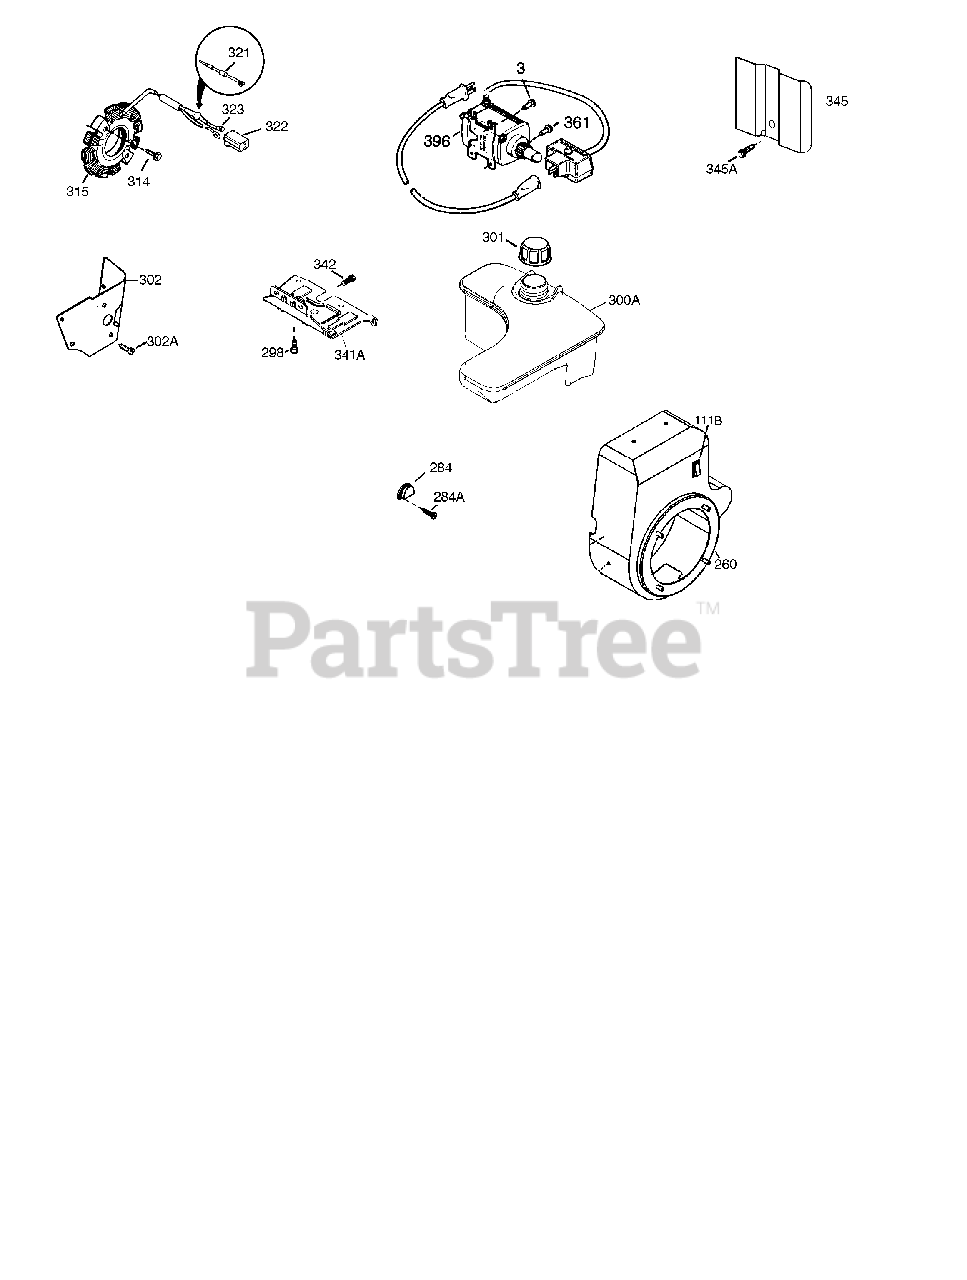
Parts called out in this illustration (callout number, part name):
260	Blower Housing
298	Screw, 1/4-15 x 3/4"
301	Fuel Cap (Red)
314	Screw, 1/4-20 x 3/4"
315	Alternator Coil (3 Amp) Incl. 321 - 3 23
322	Connector Body
323	Terminal
325	Wire Clip
341	Fuel Tank Bracket
342	Screw, 5/16-18 x 7/8"
345	Heat Baffle
370	Identification Decal
370I	Warning Decal (Bilingual)
370J	Speed Control Decal
